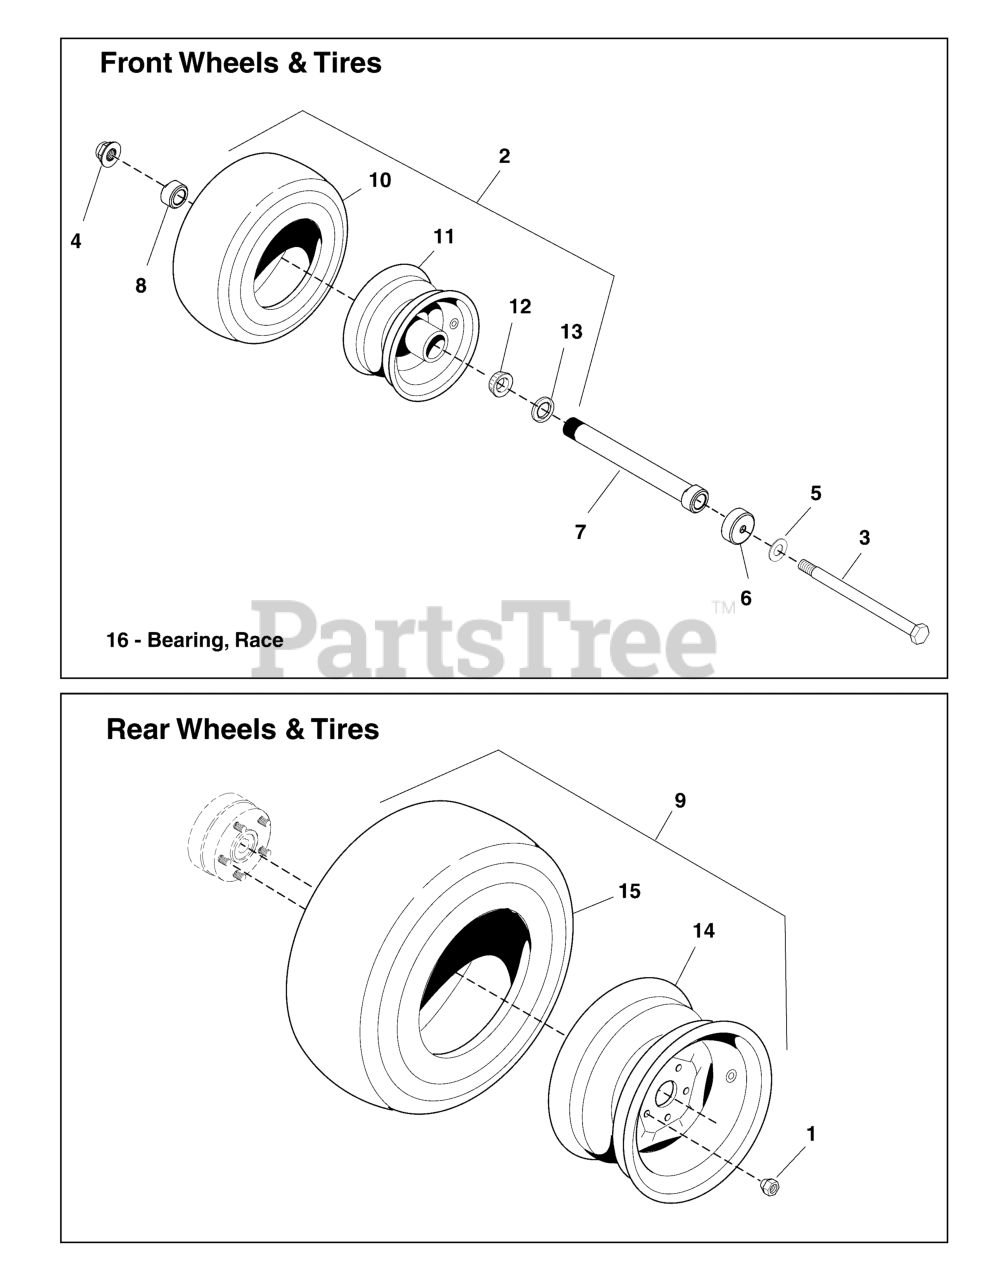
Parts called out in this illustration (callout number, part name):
1	NUT, 1/2-20, FOR WHEEL BOLT SILVER
2	TIRE ASSM, 13 X 6.5 - 6, PNE / TB
3	BOLT, 1/2-13 X 9 GD5 CZ
4	NUT, Hex Flange, Nylock, 1/2-13
5	WASHER, 1/2 SAE
6	DEBRIS, COVER, CASTER WHEELS
7	BEARING ADJUSTER, SPACER, 7.062 LG
8	NUT, BEARING ADJUSTER, AXLE
9	TIRE/WHEEL ASM, 26X12.00-12, TURF SMART
9	TIRE WHEEL ASM, 26X12.00-12, MULTI-TRAC
10	TIRE, RUBBER ONLY
11	WHEEL ASSEMBLY, FOR 13 X 6.5 X 6 TIRES (INCLUDES BEARING AND SEALS)
12	BEARING, Tapered Roller
13	SEAL, GREASE
14	WHEEL, 12 X 9.5, SOLD, 4.063" OFFSET (SV)
15	TIRE, TURF SMART, 26X12.00-12 4 PLY (SV)
15	TIRE, 26 X 12 - 12
